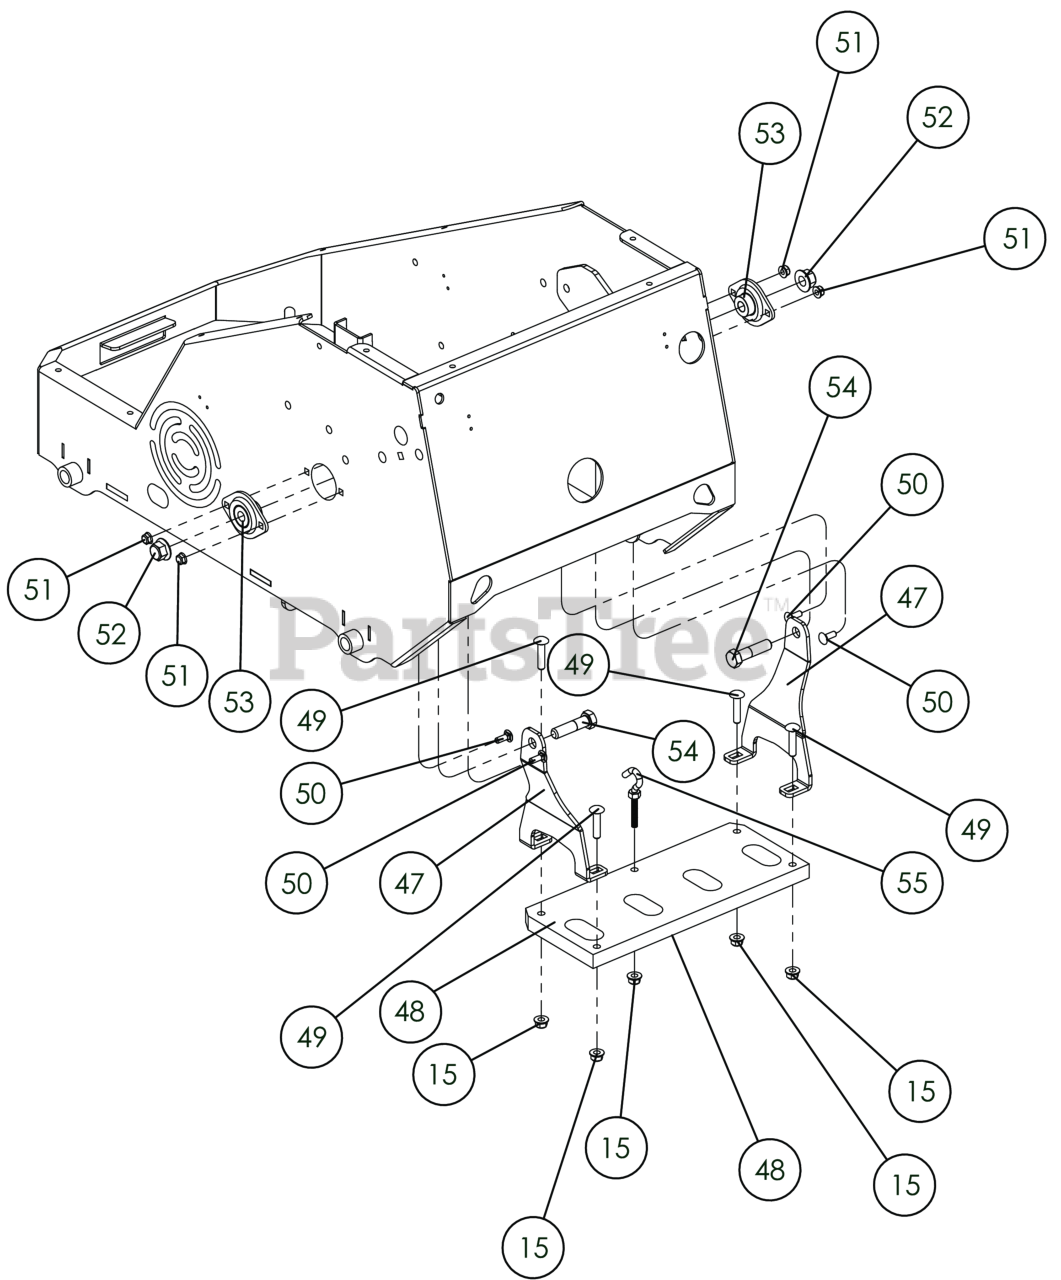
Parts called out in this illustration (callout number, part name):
15	NUT-HEX-NYLK, FLG .3125-18 ZP
47	BRKT, RETRACTOR PLATE
48	PLATE, RETRACTOR PL1801
49	BLT-RDHDSSQNK, .3125"-18 X 1.500" G5 ZP
50	BOLT CARRIAGE 1/4" X 3/4"
51	NUT-HEX-NYLK, FLG .250"-20 ZP
52	NUT-HEX-NYLK, FLG .500"-13 ZP
53	SEE: 891025-S
54	SCREWCAP 1/2"-13 X 2 GR5 ZP
55	BLT, HOOK .3125"-18 X 3.125" OAL W/NUT
